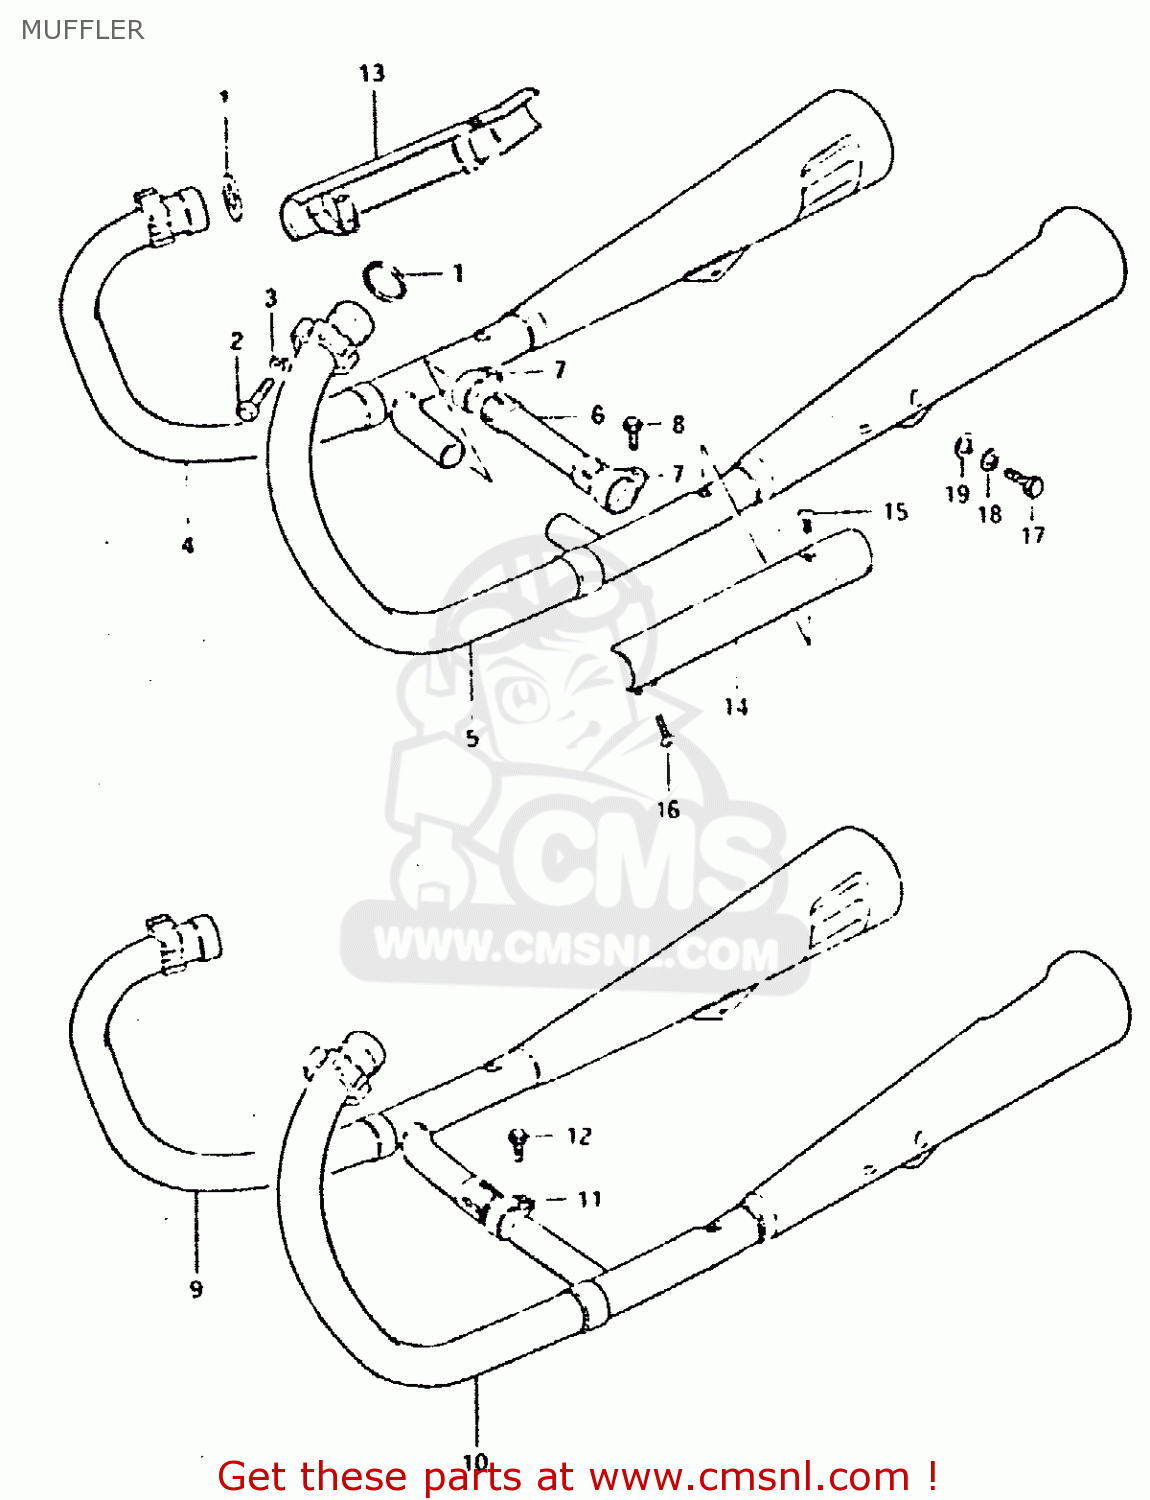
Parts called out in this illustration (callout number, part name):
1	GASKET,EXHAUST PIPE (NAS)
2	BOLT
3	LOCK WASHER
4	MUFFLER, RH
5	MUFFLER, LH
6	PIPE,EXHAUST COUPLER
7	CLAMP
8	BOLT
9	MUFFLER, RH
10	MUFFLER, LH
11	CLAMP
12	BOLT
13	COVER,MUFFLER
14	COVER,MUFFLER
15	SCREW
16	SCREW
17	BOLT 10X25
18	LOCK WASHER
19	WASHER
